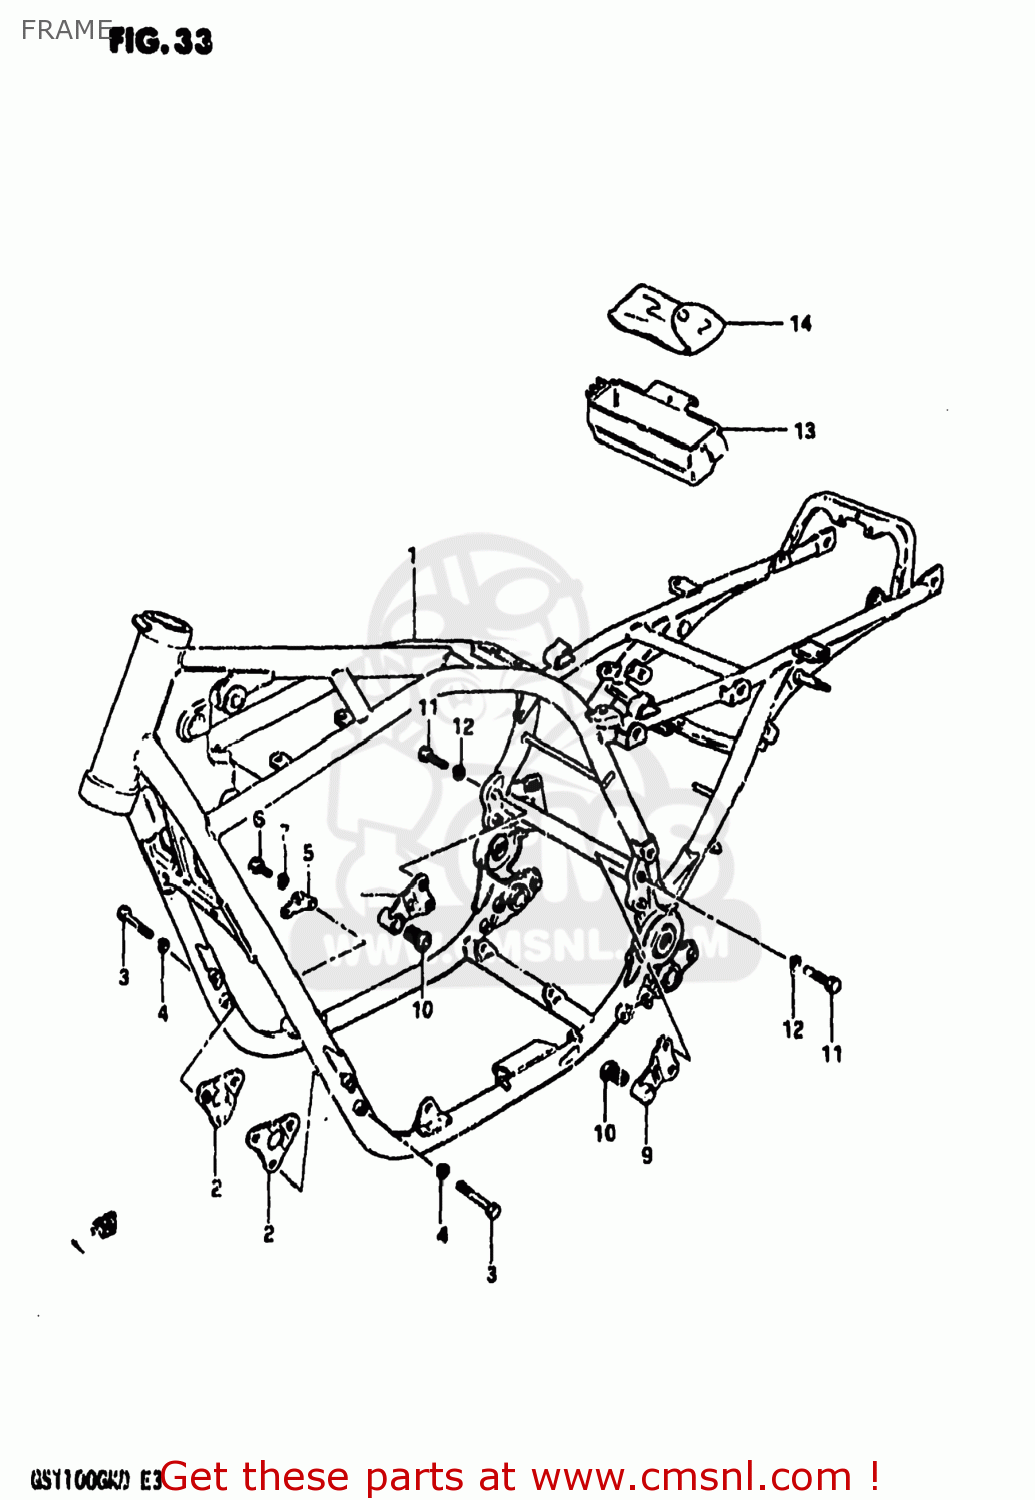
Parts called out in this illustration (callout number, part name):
1	FRAME
2	PLATE,ENGINE MOUNTING
3	BOLT
4	LOCK WASHER
5	PLATE,ENGINE MOUNTING
6	BOLT
7	LOCK WASHER
8	PLATE,ENGINE MOUNTING
9	PLATE,ENGINE MOUNTING
10	BUSHING
11	BOLT 8X40
12	LOCK WASHER
13	HOLDER,TOOL
14	TOOL SET
